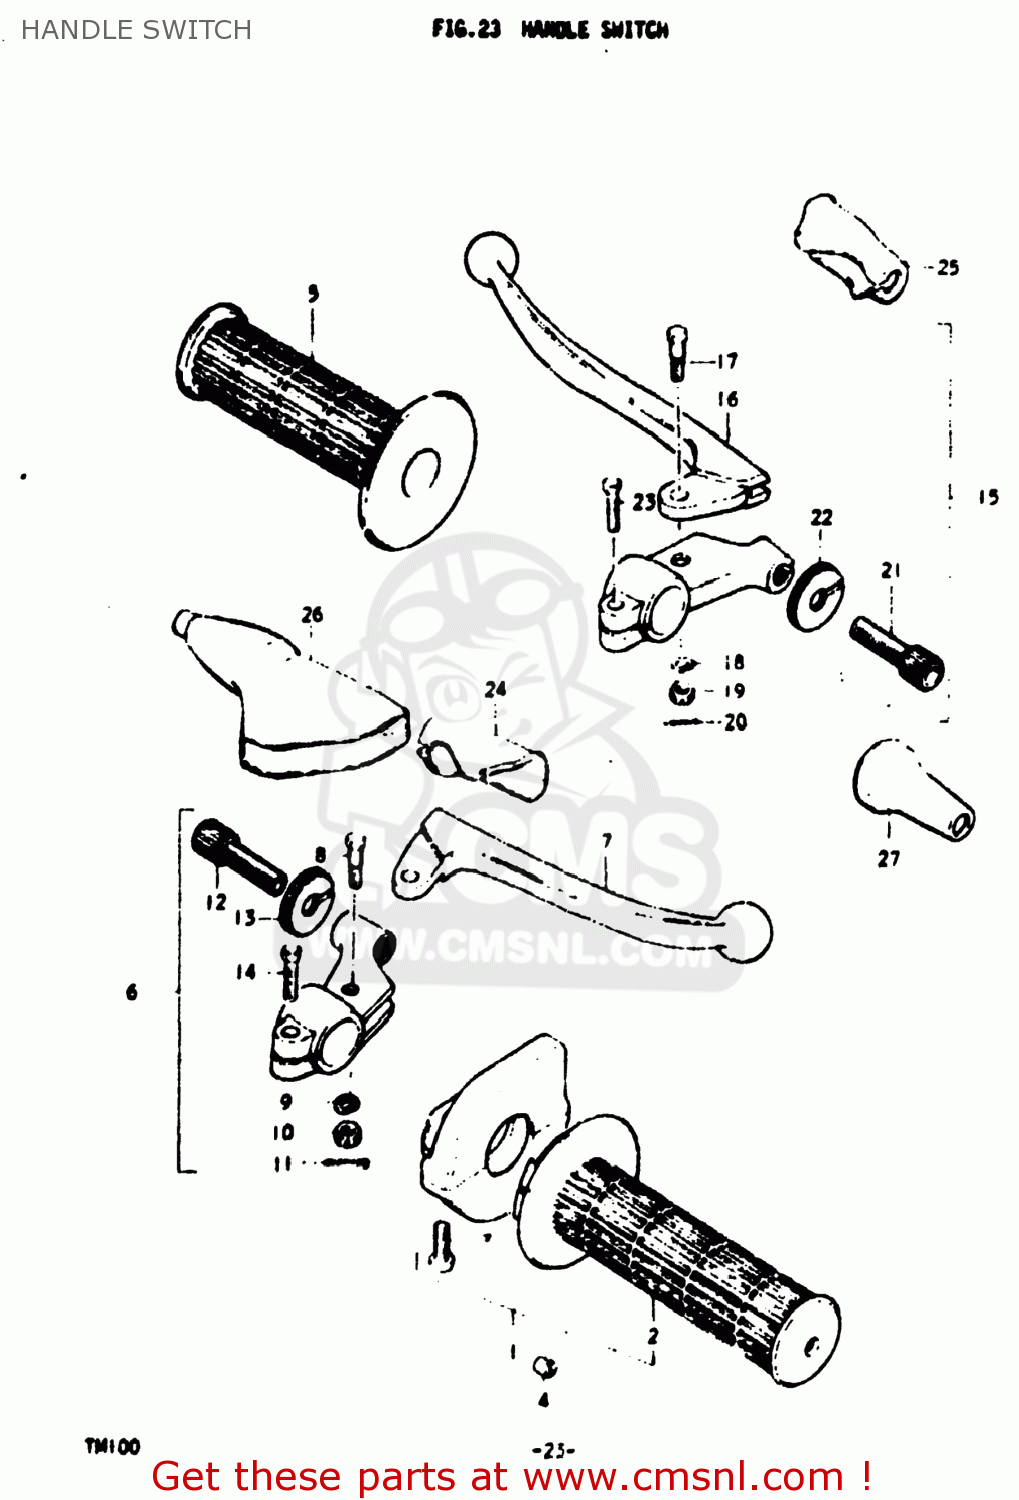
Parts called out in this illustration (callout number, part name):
1	CASE ASSEMBLY,THROTTLE
2	GRIP,THROTTLE
3	SCREW
4	PIECE,THROTTLE END
5	GRIP,LEFT
6	LEVER ASSEMBLY,BRAKE
7	LEVER,BRAKE
8	BOLT,LEVER
9	LOCK WASHER
10	NUT,LEVER FITTNG
11	COTTER PIN
12	ADJUSTER,CABLE
13	NUT,CABLE ADJUSTER
14	BOLT
15	LEVER ASSEMBLY
16	LEVER,CLUTCH
17	BOLT,LEVER
18	LOCK WASHER
19	NUT,LEVER FITTNG
20	COTTER PIN
21	ADJUSTER,CABLE
22	NUT,CABLE ADJUSTER
23	BOLT
24	COVER,BRAKE LEVER DUST
25	COVER,CLUTCH LEVER
26	COVER,CLUTCH LEVER
27	BOOT,CLUTCH CABLE
